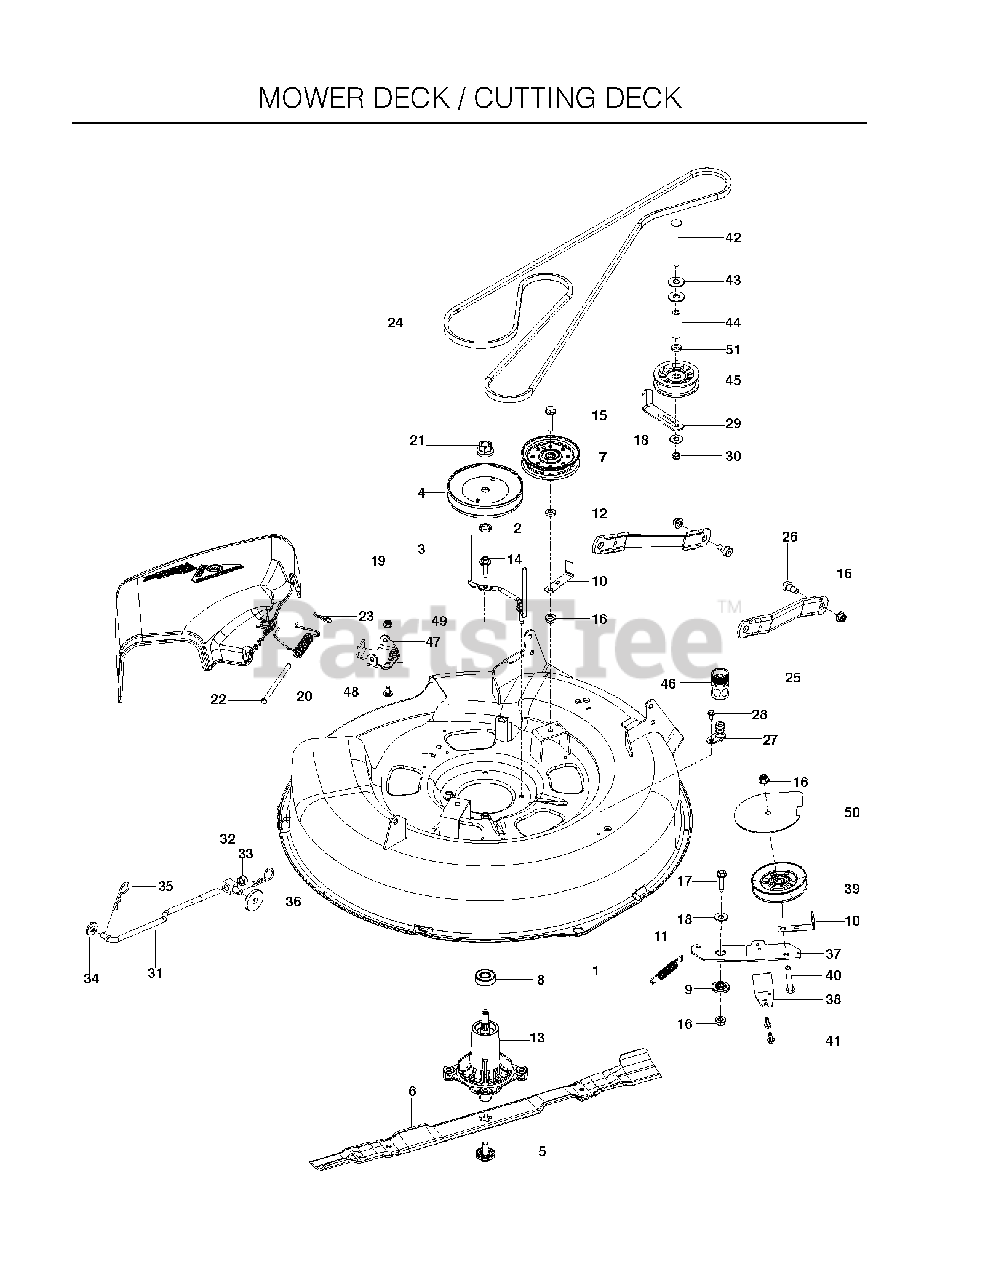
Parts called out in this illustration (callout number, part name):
1	DECK.STMPD.W/DECALS.30".BLUE.D
2	WASHER-SPACER
3	KEEPER, MANDREL BELT
4	PULLEY MANDREL 5.0"
5	BOLT.WASHER.ASM.7/16-2
6	BLADE.MOWER.BAGGING.30"
7	PULLEY.IDLER.FLAT.46.PR.DR.
8	BEARING, BALL
9	SPACER.RETAINER
10	KEEPER, BELT, BLACK
11	SPRING RETURN
12	WASHER 3/8 X 3/4 X .187 TK
13	MANDREL GREASABLE
14	WASHER HEAD SCREW
15	BLT 3/8-16X1-3/4 WHIZLK ZN SP
16	NUT 3/8-16 HEX FLG NYLOC ZD
17	BOLT 3/8-16 X 1 1/2 ZINC CLEAR
18	WASHER 3/8 FLAT
19	SHIELD.DEFLECT.MWR.30S.BLACK
20	TORSION SPRING
21	LOCKNUT - 9/16
22	PIN-CLEVIS 5/16 DIA X 5.19 ZD
23	HAIRPIN #2
24	BELT, 100" EL
25	ARM.SUSPENSION.MOWER
26	SB 3/8-16 X 3/8 SKT HD ZD
27	PORT.WASHOUT
28	BOLT 1/4-20 X 1/2 HWST
29	GUIDE, BELT
30	NUT 3/8-16 HEX JAM
31	LINK LIFT SUSP. FRONT MOWER
33	NUT, 7/16-20 HEX NYLOC ZC
34	WASHER 1/2" FLAT
35	HAIRPIN #4
36	SPINDLE WASHER
37	ARM, IDLER, BLK
38	ARM, LH BRAKE
39	Idler Pulley, 4.25
40	HCS 3/8C X 2
41	SCREW- 1/4-20 X 5/8
42	RHSNB 3/8-16 X 4 GR5 ZD
43	WASHER 7/16 FLAT ZD
44	SPACER .39 ID X 2.25
45	PULLEY, IDLER
46	COUPLING.QUICK CONNECT
47	BRKT.DEFLECTOR.38"2005+
48	CARRIAGE BOLT 5/16C X 5/8"
49	5/16-18 NYLOC FLANGE NUT
50	WASHER 3/8 X 3/4 X .187 TK
51	COVER, PULLEY, BLACK
